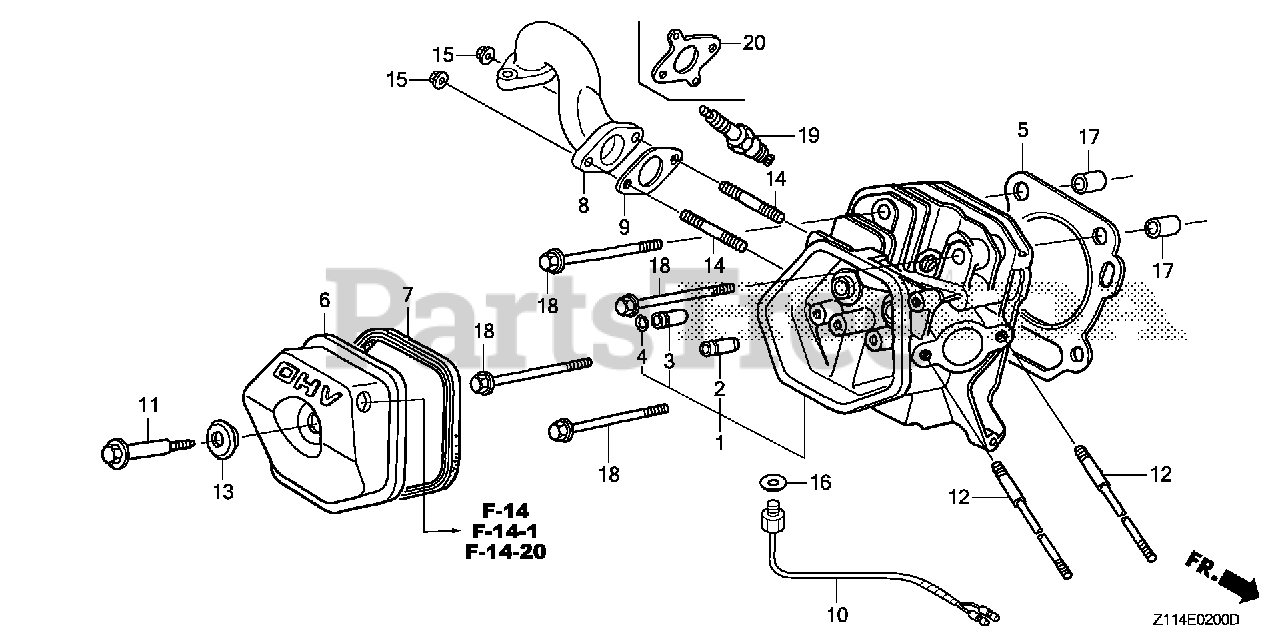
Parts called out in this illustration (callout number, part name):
1	CYLINDER HEAD
2	GUIDE, VALVE (OS)
3	GUIDE, EX. VALVE (OS)
4	CLIP, VALVE GUIDE
5	GASKET, CYLINDER HEAD
6	COVER, HEAD
7	GASKET, CYLINDER HEAD COVER
9	GASKET, EX. PIPE Use up to Engine SN 2949254.
9	GASKET, EX. PIPE (WACKER)
10	SENSOR ASSY., TEMPERATURE
11	BOLT, HEAD COVER
12	BOLT, STUD (8X138.5)
13	WASHER, HEAD COVER
14	BOLT 2, STUD (8X32)
15	NUT, FLANGE (8MM)
16	WASHER, PLAIN (8MM)
17	PIN A, DOWEL (12X20)
18	BOLT, FLANGE (10X80)
19	SPARK PLUG (BPR5ES) (NGK)
19	SPARK PLUG (W16EPR-U) (DENSO)
20	GASKET, EX. PIPE
